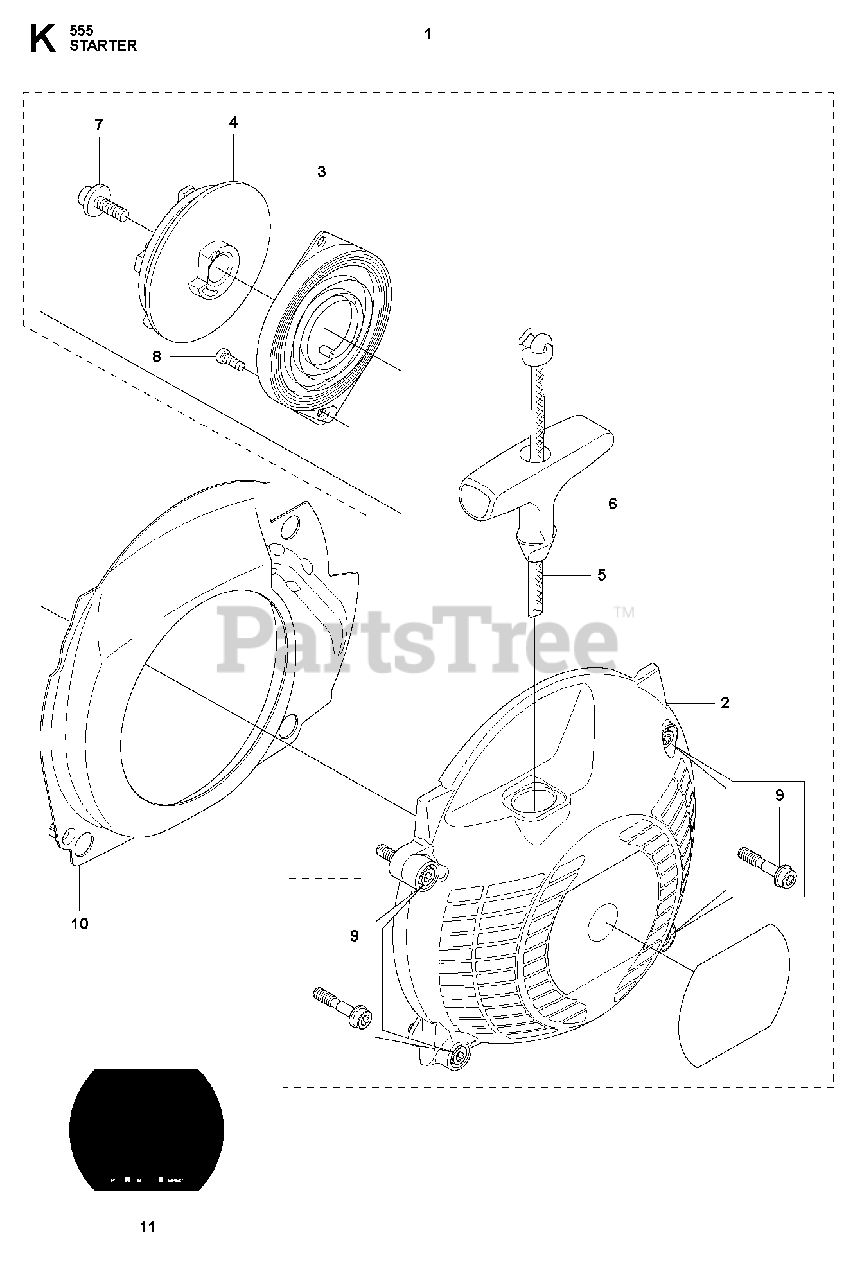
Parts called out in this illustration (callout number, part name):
1	STARTER ASSY
2	STARTER HOUSING SPARE PART IN
3	RECOIL SPRING
4	STARTER PULLEY
5	STARTER ROPE
6	HANDLE
7	SCREW
8	SCREW
9	SCREW IHSCFMO
10	AIR CONDUCTOR
